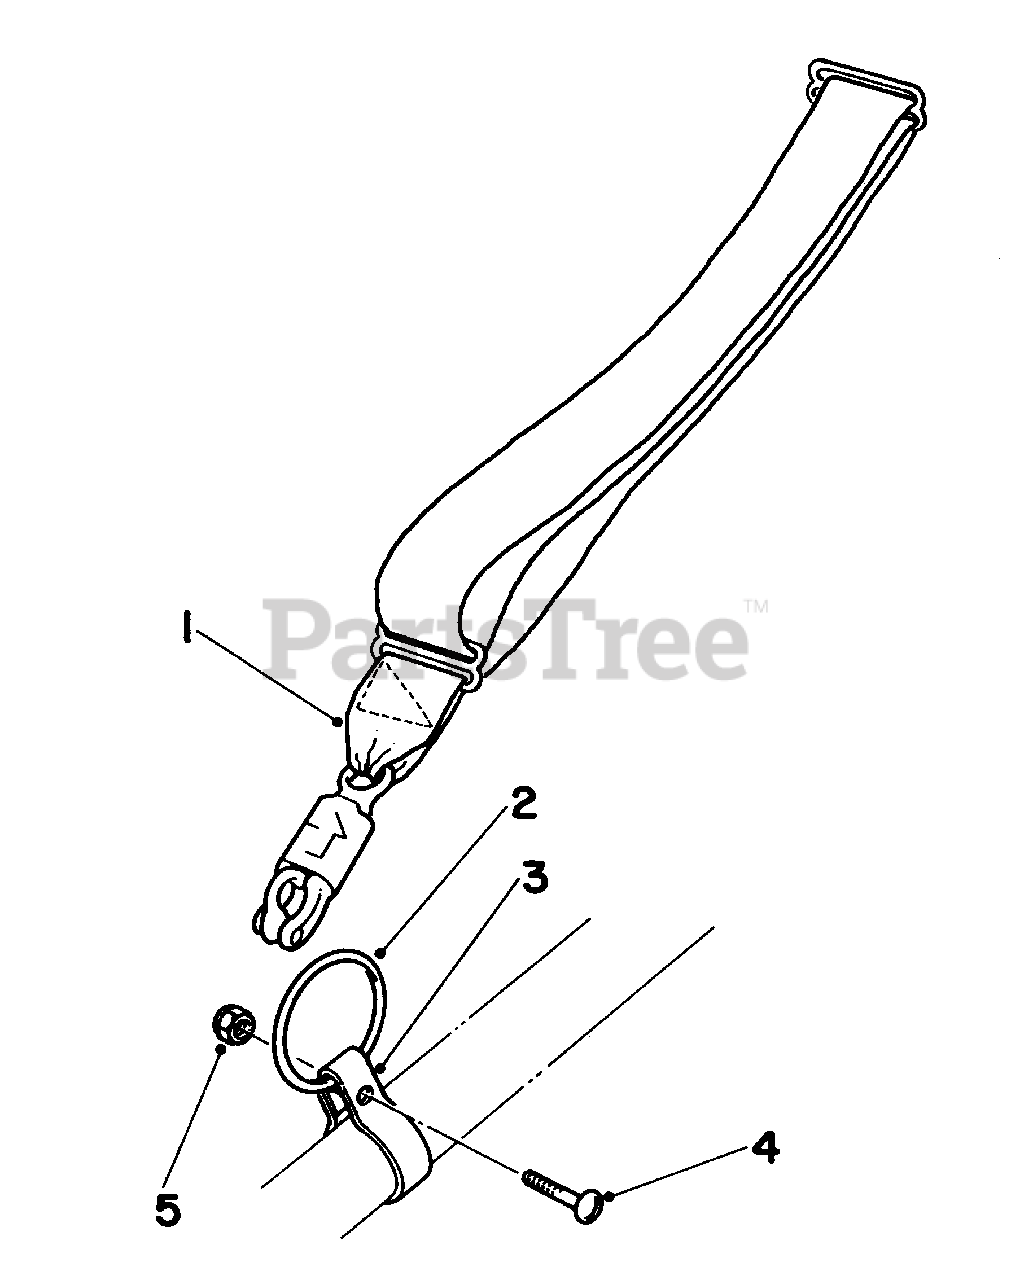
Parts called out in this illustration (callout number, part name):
1	Shoulder Harness Std.
2	Ring
3	Clamp
